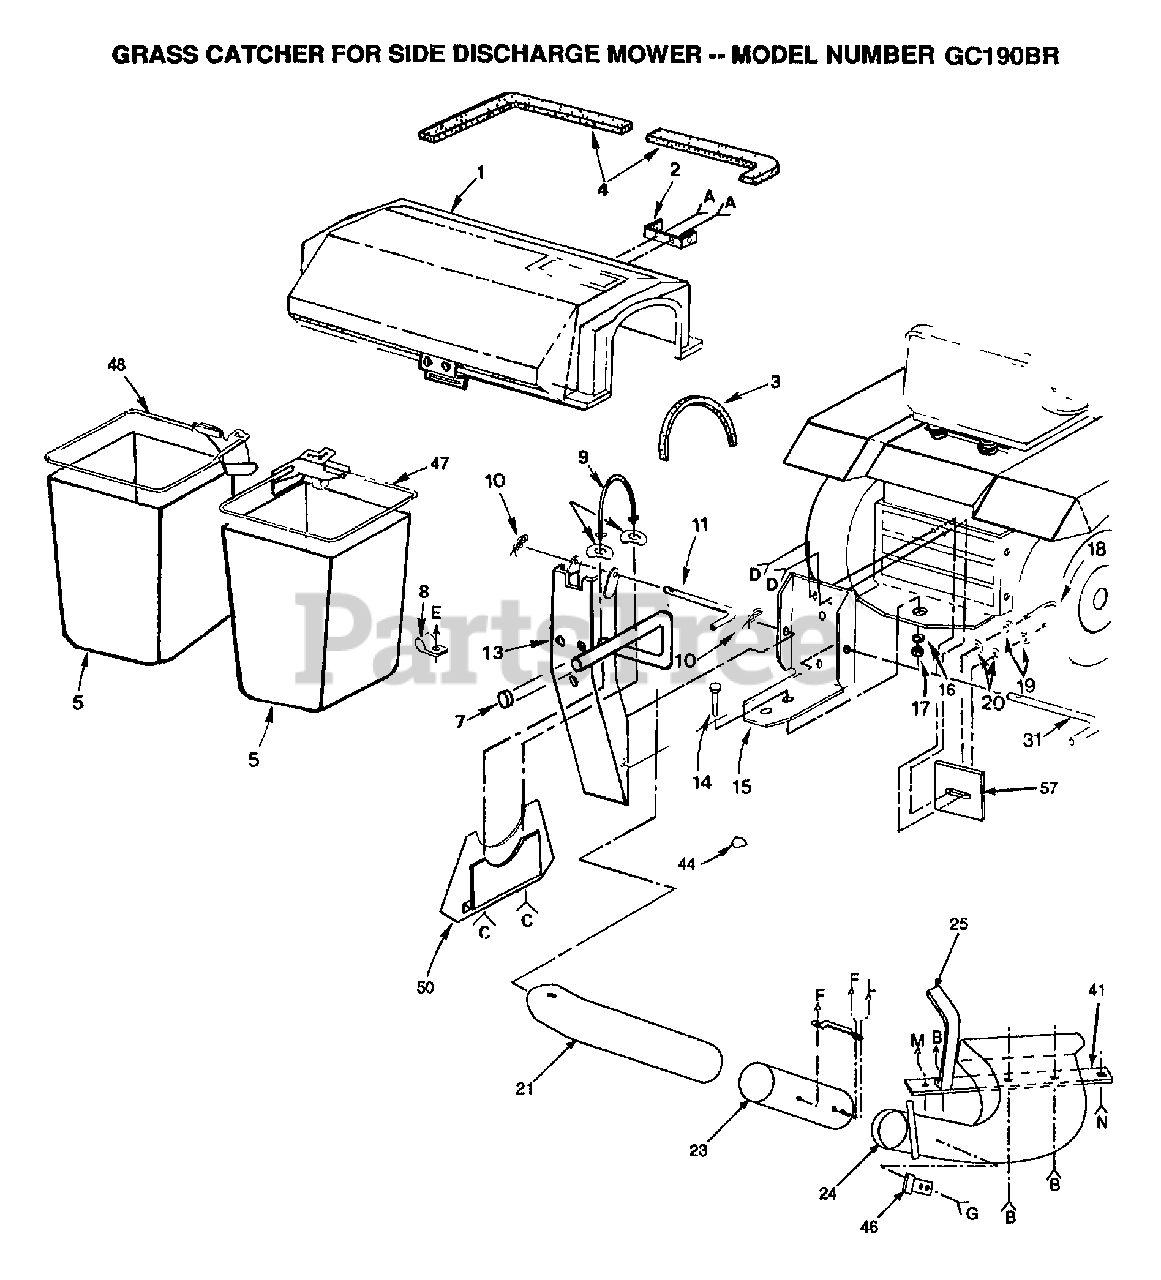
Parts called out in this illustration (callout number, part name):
2	BRACKET HINGE RB
3	FOAM.STRIP.RB
5	GRASS BAG RB
8	CLAMP
9	RETAINER RB
13	POST SUPPORT RB
16	WASHER PM
18	U BOLT RB
19	NUT
20	WASHER
44	DECAL HYT
46	HOOD LATCH T
47	ASSY FRAME RH
48	ASSY FRAME LH
